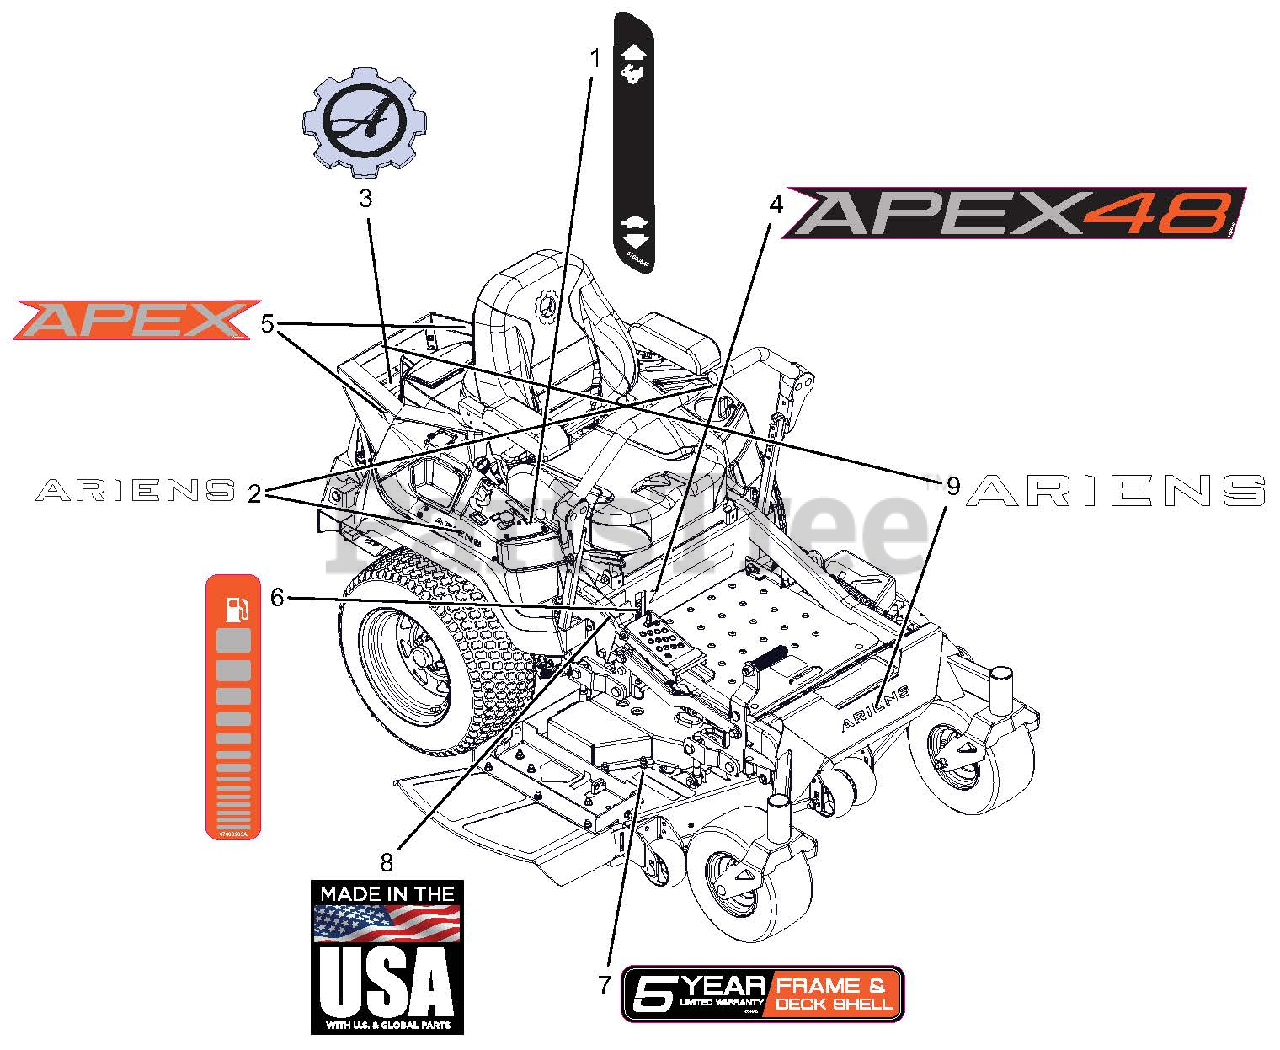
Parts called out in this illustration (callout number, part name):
1	DECAL, DASH DECAL
2	DECAL, ARIENS (6.50")
3	DECAL, ARIENS-GEAR BADGE -THK
4	DECAL, 48" APEX KICKPLATE
5	DECAL, APEX FENDER
6	DECAL, ARIENS FUEL LEVEL
7	DECAL, DECK 5 YEAR-ARIENS
8	DECAL, MADE IN USA
9	DECAL - ARIENS 9.625"
